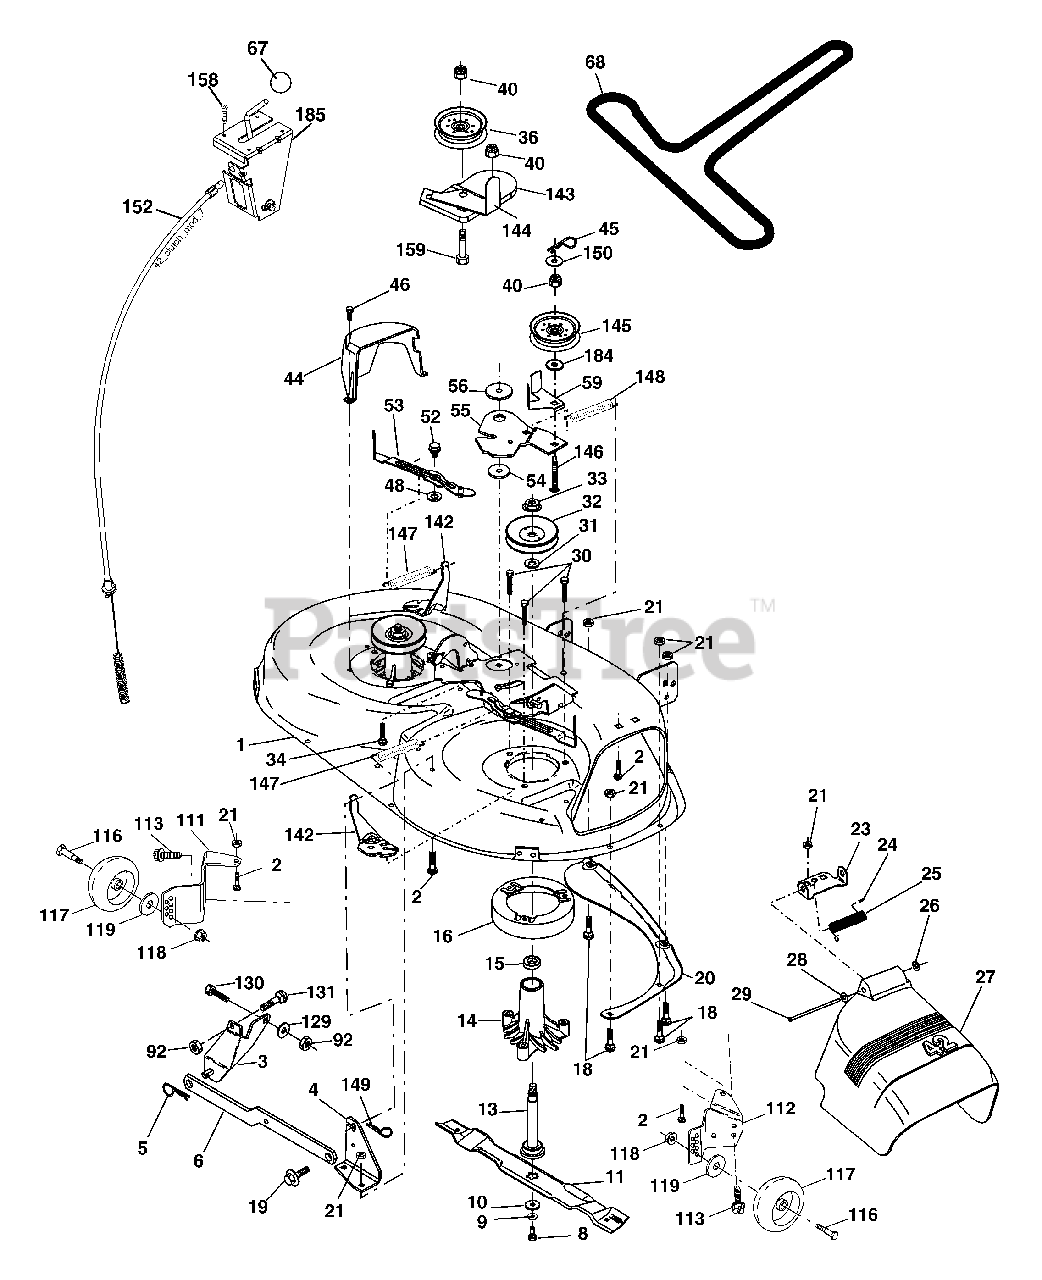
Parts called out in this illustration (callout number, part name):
1	Deck Asm MWR 42"weldment
2	Bolt Rdhd Sqnk 5/16-18 unc x 3/4
3	Bracket Asm Fr Sway Bar 38/42
4	Bracket Asm Deck 42"sway Bar
5	Retainer Spring
6	Deck Sway Bar
8	Bolt 3/8 - 24 x 1.25 Gr. 8
9	Washer Lock Hvy 3/8
10	Washer Hard Blade Mower Vented
11	Blade, 42" Hi-Lift
11	Blade Mower 42"
11	Blade, 42" Mulching Premium
13	Shaft Asm W/lower Bearing
14	Housing Mandrel Vented
15	Bearing Ball Mandrel
16	Stripper Mower
18	Bolt Rdhd Sqnk 5/16-18 x 5/8
19	Bolt Shoulder
20	Baffle Vortex 42
21	Nut Crownlock 5/16-18 unc
23	Bracket Deflector Mower 42"
24	Cap Sleeve 80 x 112 Blk Mower
25	Spring Torsion Deflector 2 52
26	Nut Push Phos & Oil
27	Shield Deflector Mower 42" Blk
28	Washer 11/32 x 5/8 x 16 Ga.
29	Rod Hinge 42" 6 75 Wlg
30	Screw Thd Rolling
31	Washer Spacer
32	Pulley Mandrel 42"
33	Nut Toplock Flng
34	Bolt Rdhd 3/8-16 unc x 1-1/2 Gr. 5
36	Pulley Idler Flat
40	Nut Lock 3/8-16 unc
44	Guard Mandrel LH Black
45	Spring Retainer 1" Zinc/cad
46	Screw Hex Thd Cut 1/4-20 x 5/8 T
48	Washer Hardened Smaller
52	Bolt Shoulder 5/16-18 unc Blkz
53	Arm Asm Pad Brake
54	Washer Hardened
55	Arm Idler 42"mower LT/YT
56	Spacer Retainer Mower
59	Guard TUV Idler
67	Knob Rd 3/8-16 Plstc Thds Blk
68	V-Belt Mower 42"
92	Nut 3/8-16 unc
111	Bracket Wheel Guage LH
112	Bracket Wheel Guage RH
113	Bolt 5/16-18 Hex Whs-Hd Lck Ser.
116	Bolt Shoulder
117	Wheel Guage
118	Nut Lock 3/8-16 unc
119	Washer 3/8 x 7/8 x 14 Ga.
129	Washer 13/32 x 13/16 x 12 Ga.
130	Bolt 3/8-16 x 1 Gr. 5
131	Bolt 3/8-16 x 1
142	Arm Spring Brake Mower
143	Bracket Arm Idler 42"
144	Keeper Belt 42" Clutch
145	Pulley Idler Flat
146	Bolt Carriage Idler
147	Spring Extension
148	Spring Return Idler
149	Retainer Spring Yellow
150	Washer 9/32 x 3/4 x 10 Ga.
152	Clutch Cable 42"
158	Screw Hex Thd Cut 1/4-20 x 1/2
159	Bolt Rdhd Sqn 3/8-16 unc x 1-3/4
184	Washer 13/32 x 7/8 x 10 Ga.
185	Head Asm. Cable Clutch
